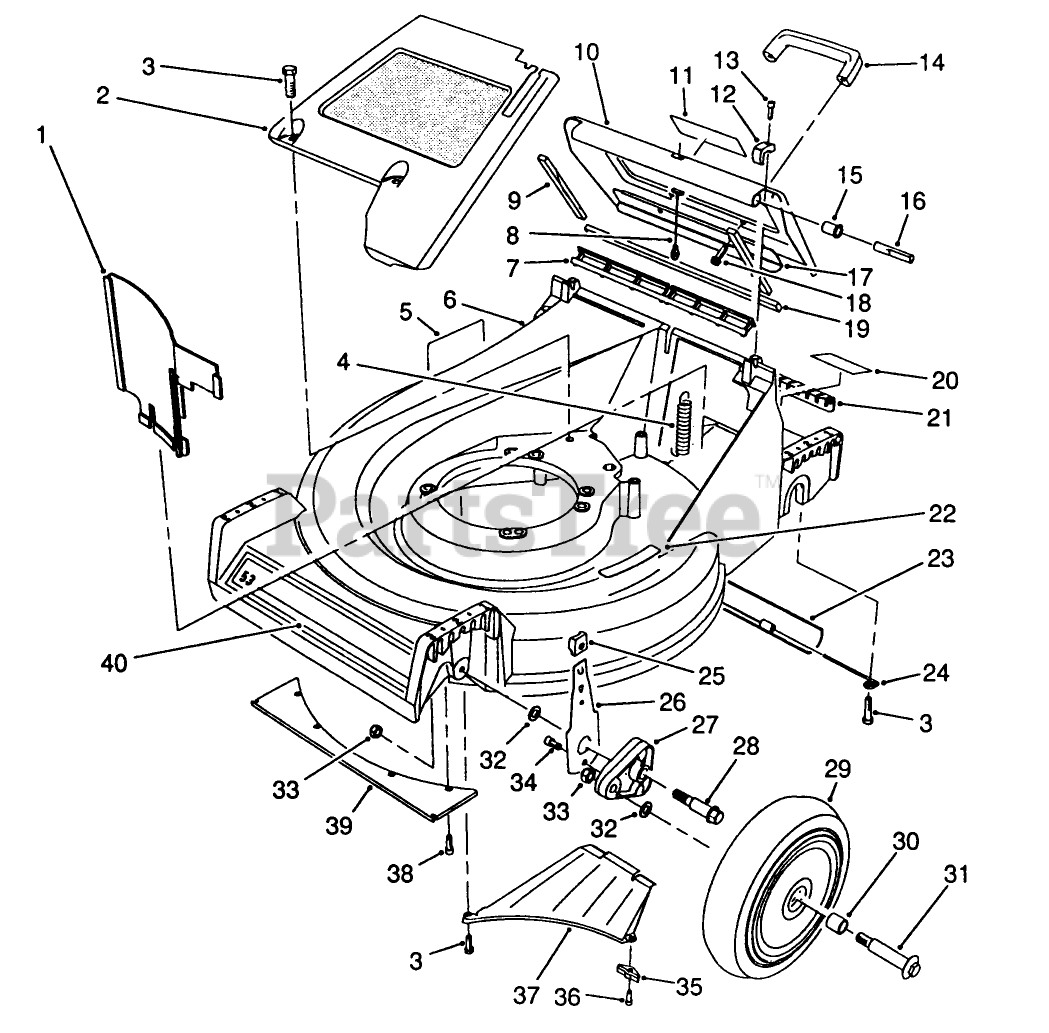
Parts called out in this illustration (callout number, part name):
1	PANEL-VERTICAL
3	SCREW-HWHTF
4	SPRING-EXTENSION
8	DOOR CABLE
13	SCREW-HSH
14	HANDLE-DOOR
15	DOOR BUSHING
18	SCREW-HWH
19	DOOR END SEAL
21	ACCESS COVER
22	DECAL - STEP PAD INT'L
23	TRAILING SHIELD
25	KNOB-ARM
26	FRONT SPRING ARM ASM
27	ARM-PIVOT, FRONT
28	BOLT-SHOULDER
30	BUSHING
31	WHEEL BOLT
32	WASHER
34	SCREW-HSH, THREAD FORMING
36	SCREW-HWHTF
38	SCREW-HWH
